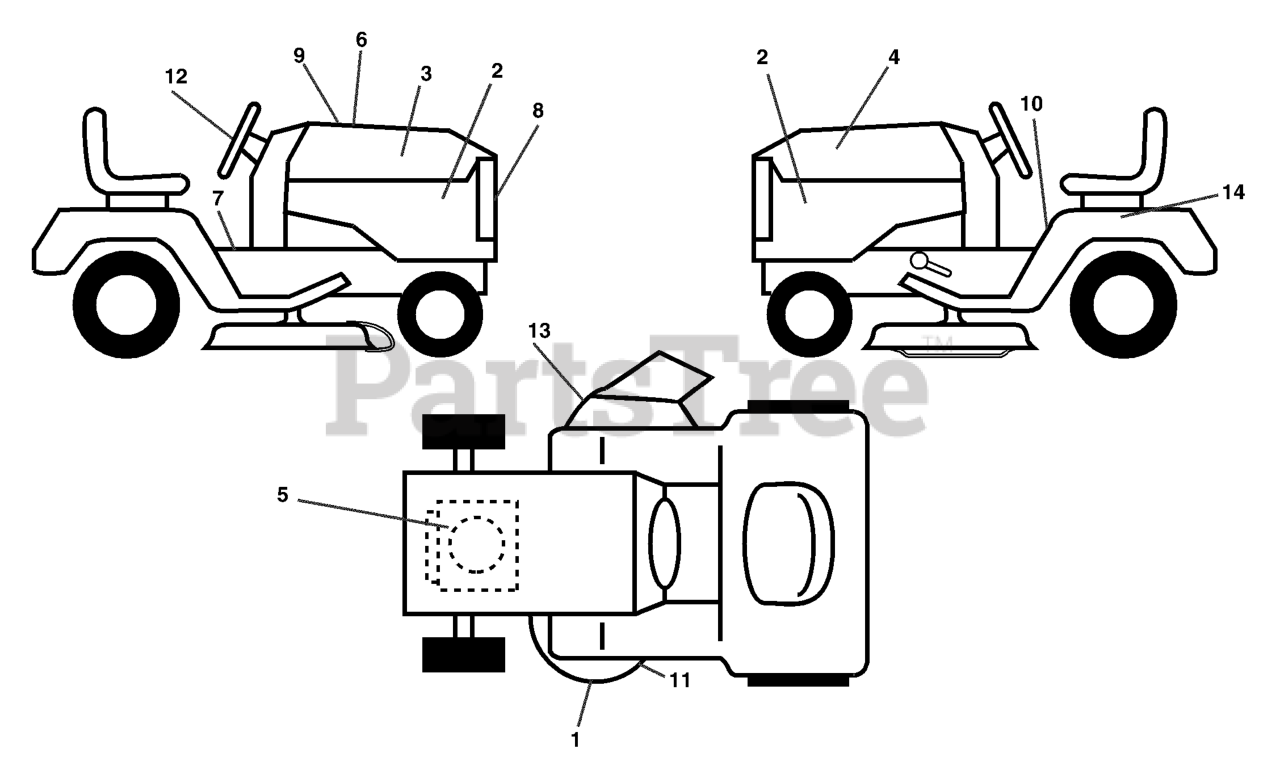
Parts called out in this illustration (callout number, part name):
1	DECAL, MOWER HEAVY DUTY
2	HOOD DECAL, YTH2148
3	DECAL, HOOD RH
4	DECAL, HOOD LH
6	DECAL HOOD CUST. RESP.
9	DECAL.RPLM.YTH2148
10	DECAL FENDER DANGER
11	DECAL V-BELT SCHEMATIC
12	DECAL.STEERING.HUSQ.BLUE
13	DECAL.WARN.KEEP.HAND.AWAY
14	DECAL BTRY SYMBOLS
